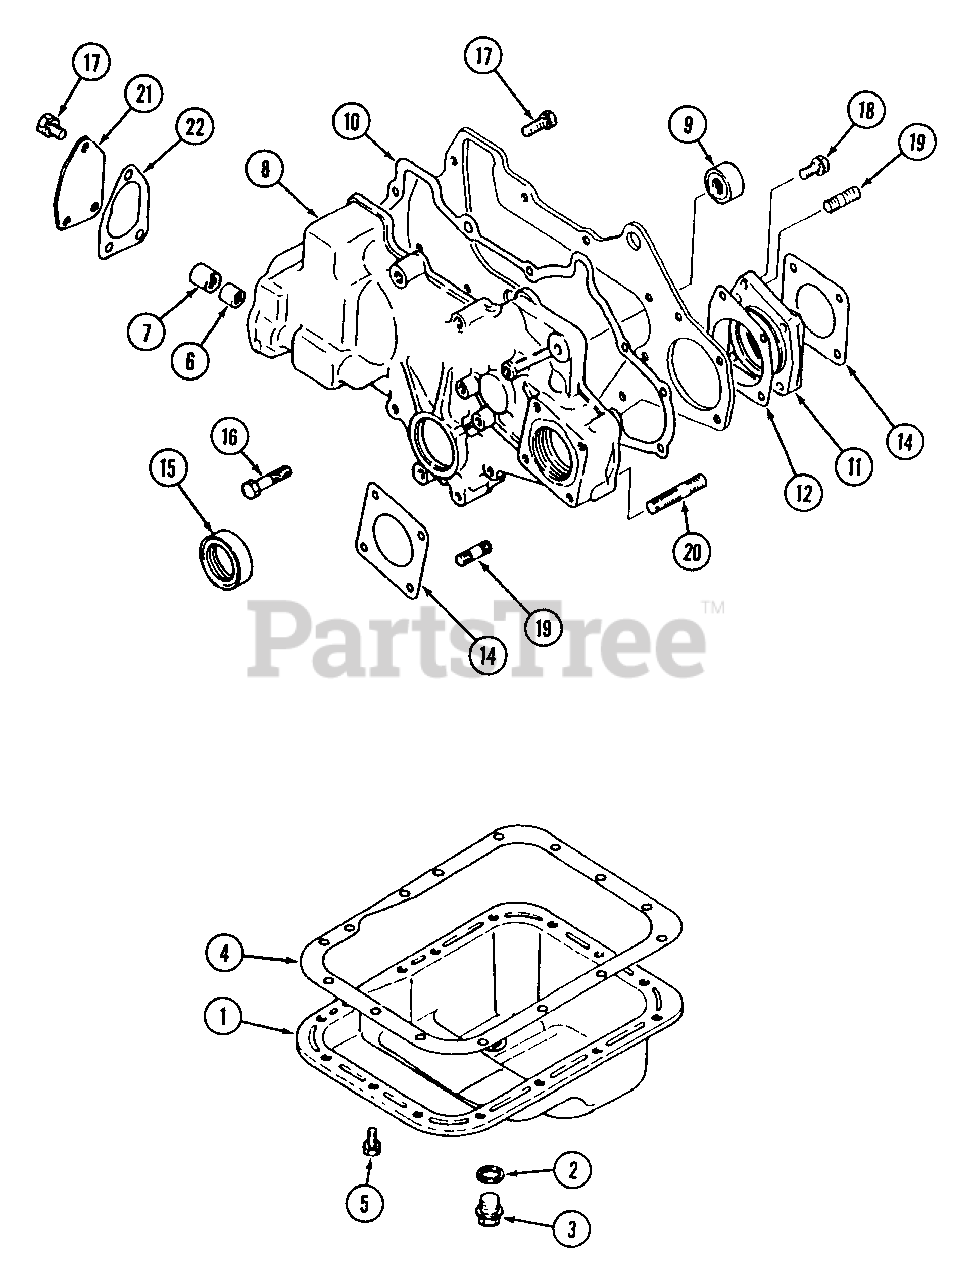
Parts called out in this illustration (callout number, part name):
1	Pan Ass'y., Oil
2	Gasket, Drain Plug
3	Plug, Oil Drain
4	Gasket, Oil Pan
5	Bolt,
6	Bearing, Needle
7	Bearing, Needle
9	Plug, Thrust
10	Gasket, Gear Case
11	Housing, Pump Gear
12	Gasket, Housing
14	Gasket, Oil Pump
17	Bolt,
18	Bolt,
21	Cover, Governor
22	Gasket, Governor Cover
